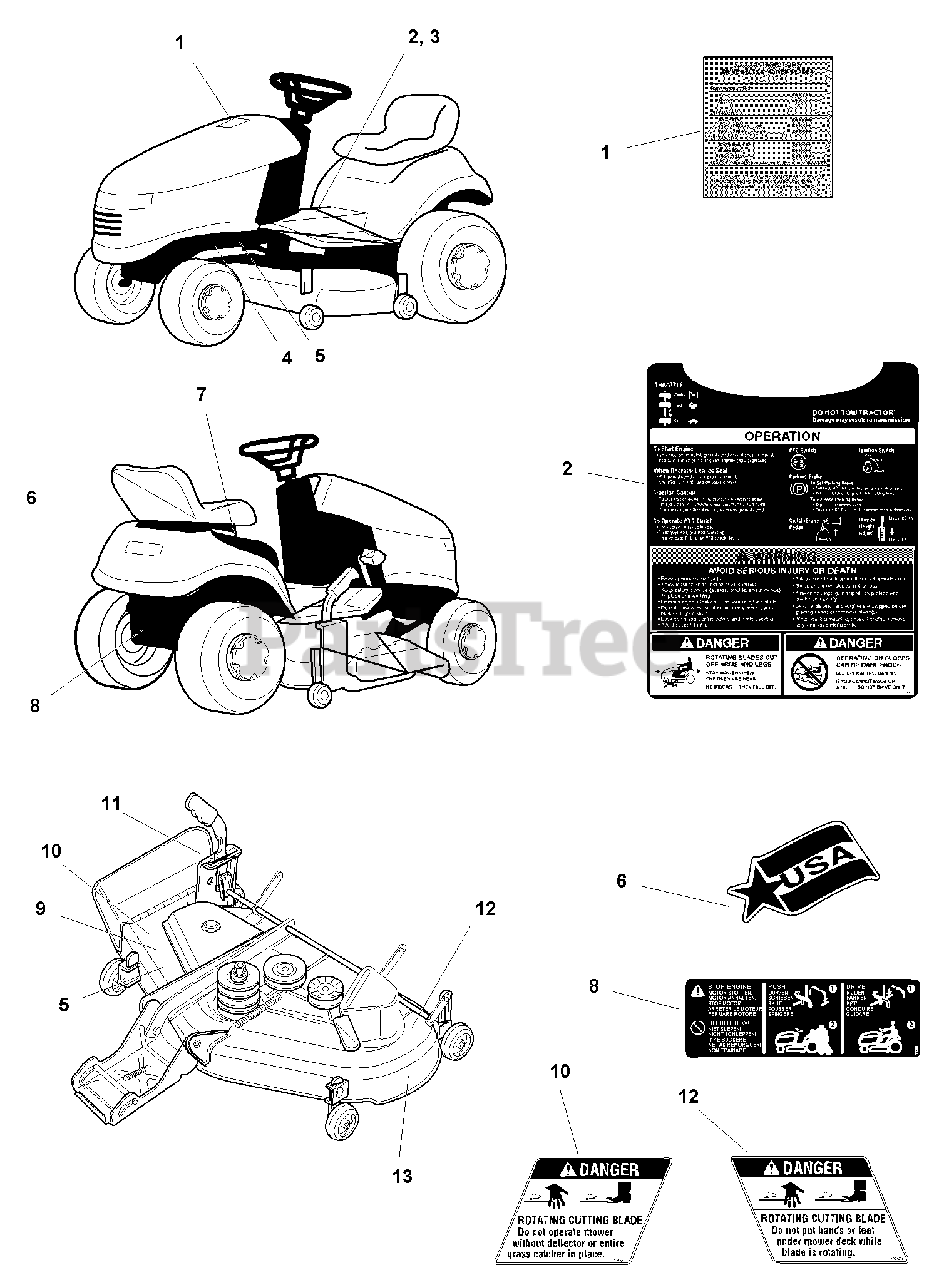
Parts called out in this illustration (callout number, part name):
1	DECAL, Belts & Mower Blades
2	DECAL, Operating Instructions
4	DECAL, Patent
5	DECAL, OPEI (Not Serviced)
5	DECAL, Serial Number (Not Serviced)
6	DECAL, USA Logo
7	DECAL, PTO Control Symbols
8	DECAL, Transmission Release Valve, Hydros only
10	DECAL, DANGER
11	DECAL, Height Of Cut
12	DECAL, DANGER
13	DECAL, Free Floating Mower
